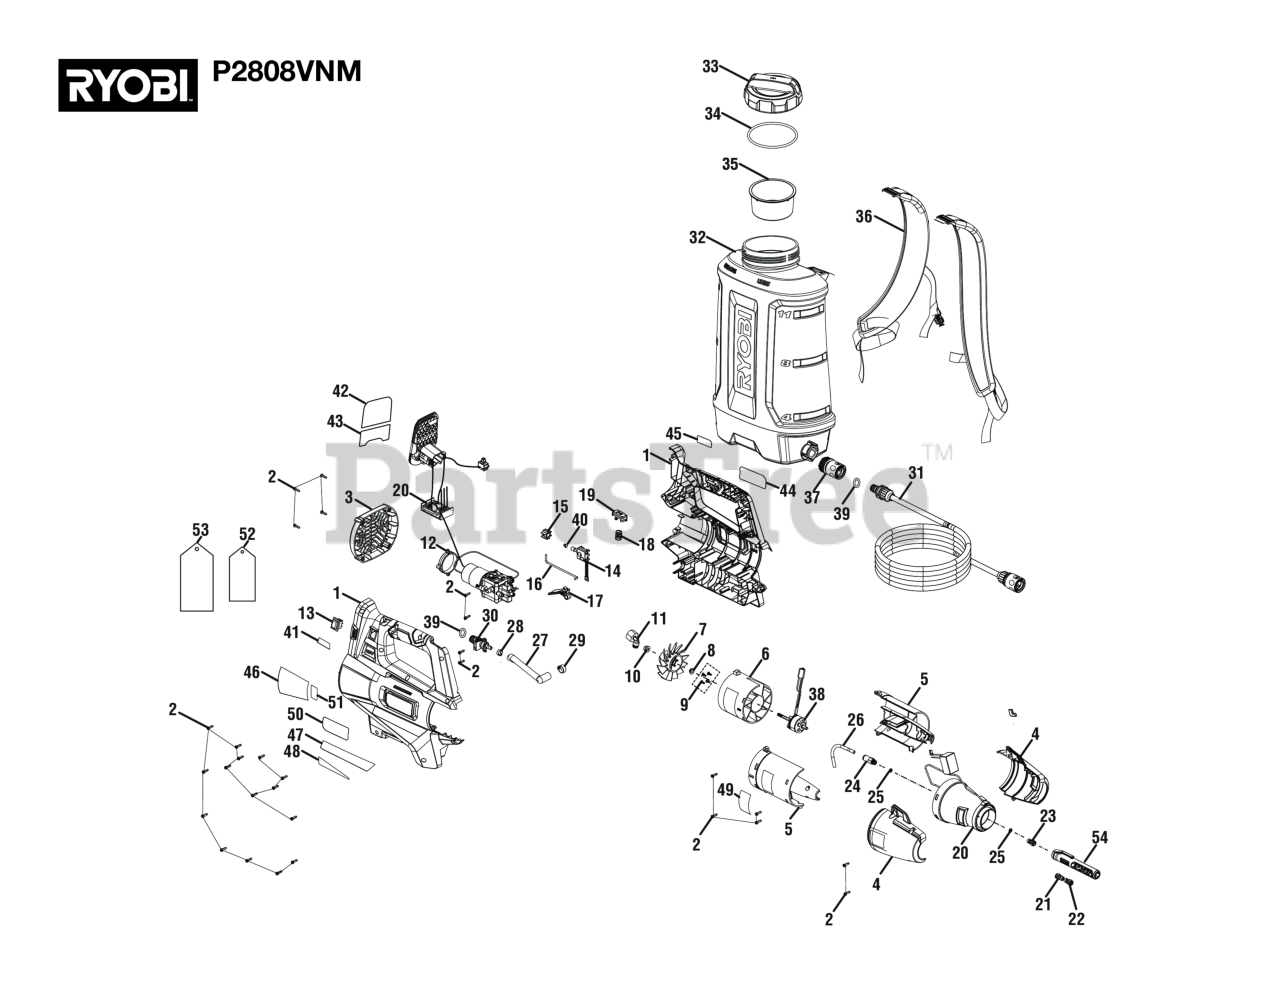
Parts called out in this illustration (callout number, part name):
1	Housing Assembly (Inc. Key Nos. 44-48 & 50-51)
2	Screw (M4 x 14 mm, T15 Torx Pan Hd.))
3	Blower Cover
4	Outlet Tube Assembly
5	Cone Assembly (Inc. Key No. 49)
6	Motor Mount
9	Screw (M3 x 8 mm, Pan Hd.)
10	Flange Lock Nut (M6 x 1 mm)
12	Pump Mount
13	On/Off Switch
15	Switch Cap
16	Trigger Rod
17	Switch Trigger
19	Spray Button
20	Motor Controller, Switch, and Pump Assembly (Inc. Key Nos. 42-43)
21	Nozzle (Medium)
22	Nozzle (High)
23	Nozzle (Low)
24	Push Connect
30	Male Quick Connect
31	Tube Assembly (Inc. Key No. 39)
32	Tank Assembly (Inc. Key Nos. 33-37)
33	Tank Cap Assembly
35	Inlet Filter
37	Shut-off Valve
39	O-Ring (ID11.3 x CS2.5)
40	Compression Spring for Trigger
41	On/Off Label
42	Data Label
43	Clean Tank and Lines Label
44	RYOBI ONE+ HP Label
45	ONE+ HP Logo Label
46	Icon/Danger Label
47	Warning Label (French)
48	Warnings Label (Spanish)
49	Caution w/Arrow Label
50	Shoes Caution Label
52	Instruction Tag (Portuguese)
53	Instruction Tag
54	ES Blower Nozzle Tool
